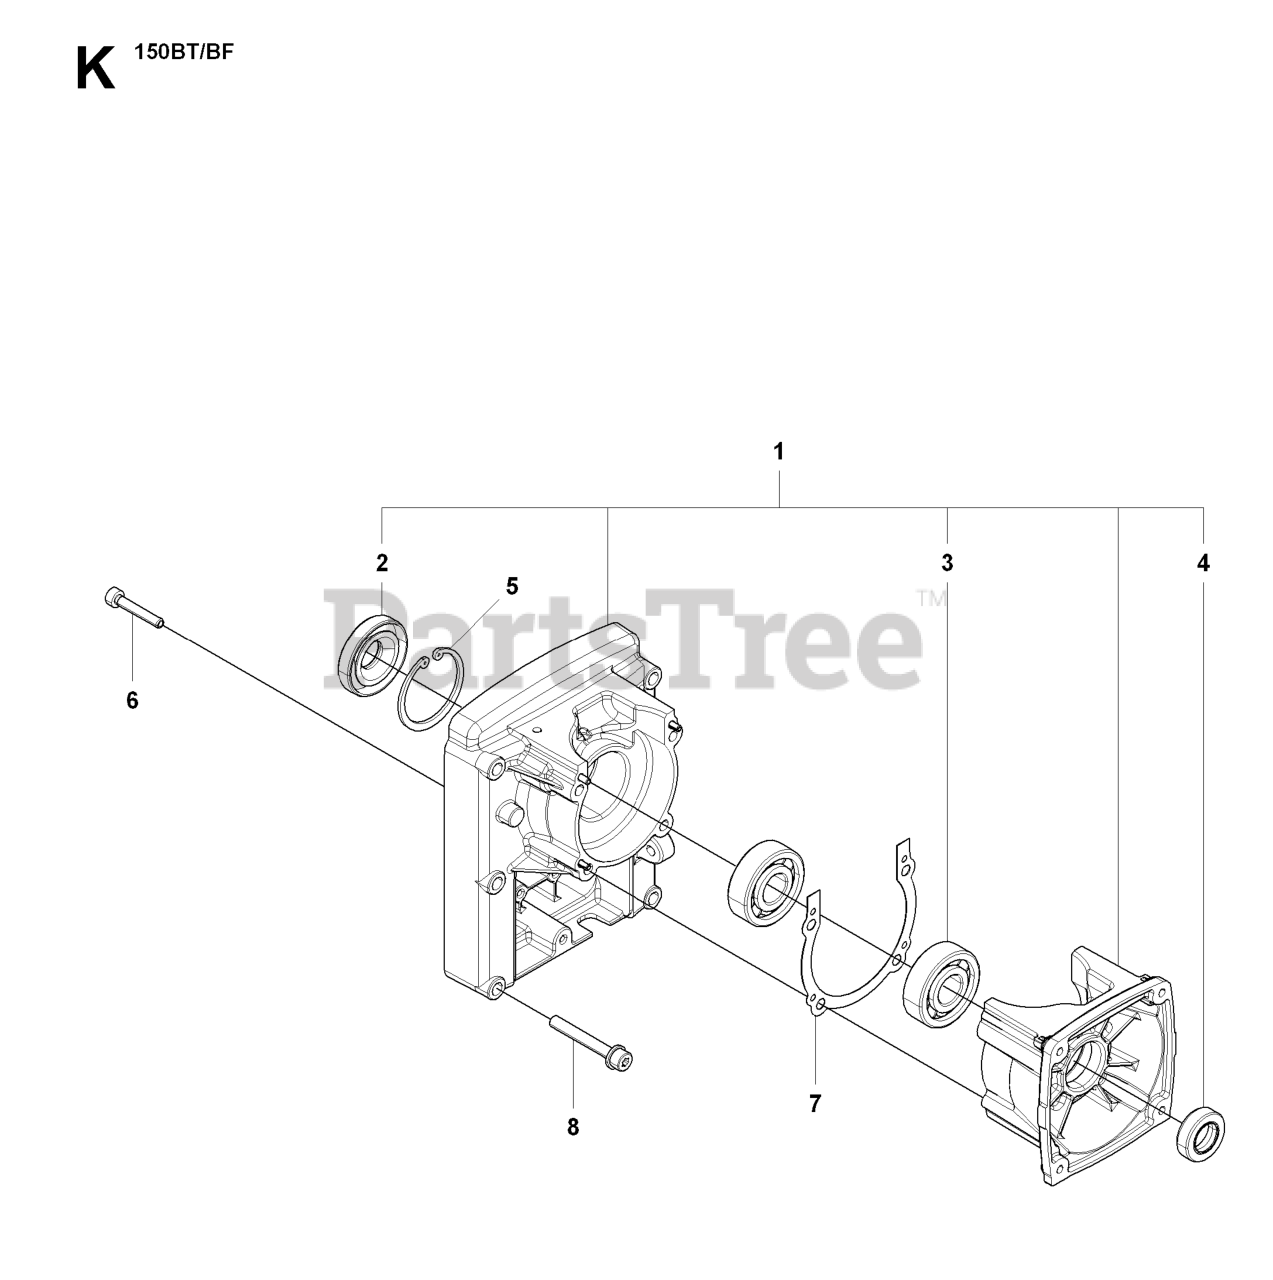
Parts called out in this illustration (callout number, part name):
3	BEARING
6	BOLT
8	BOLT
